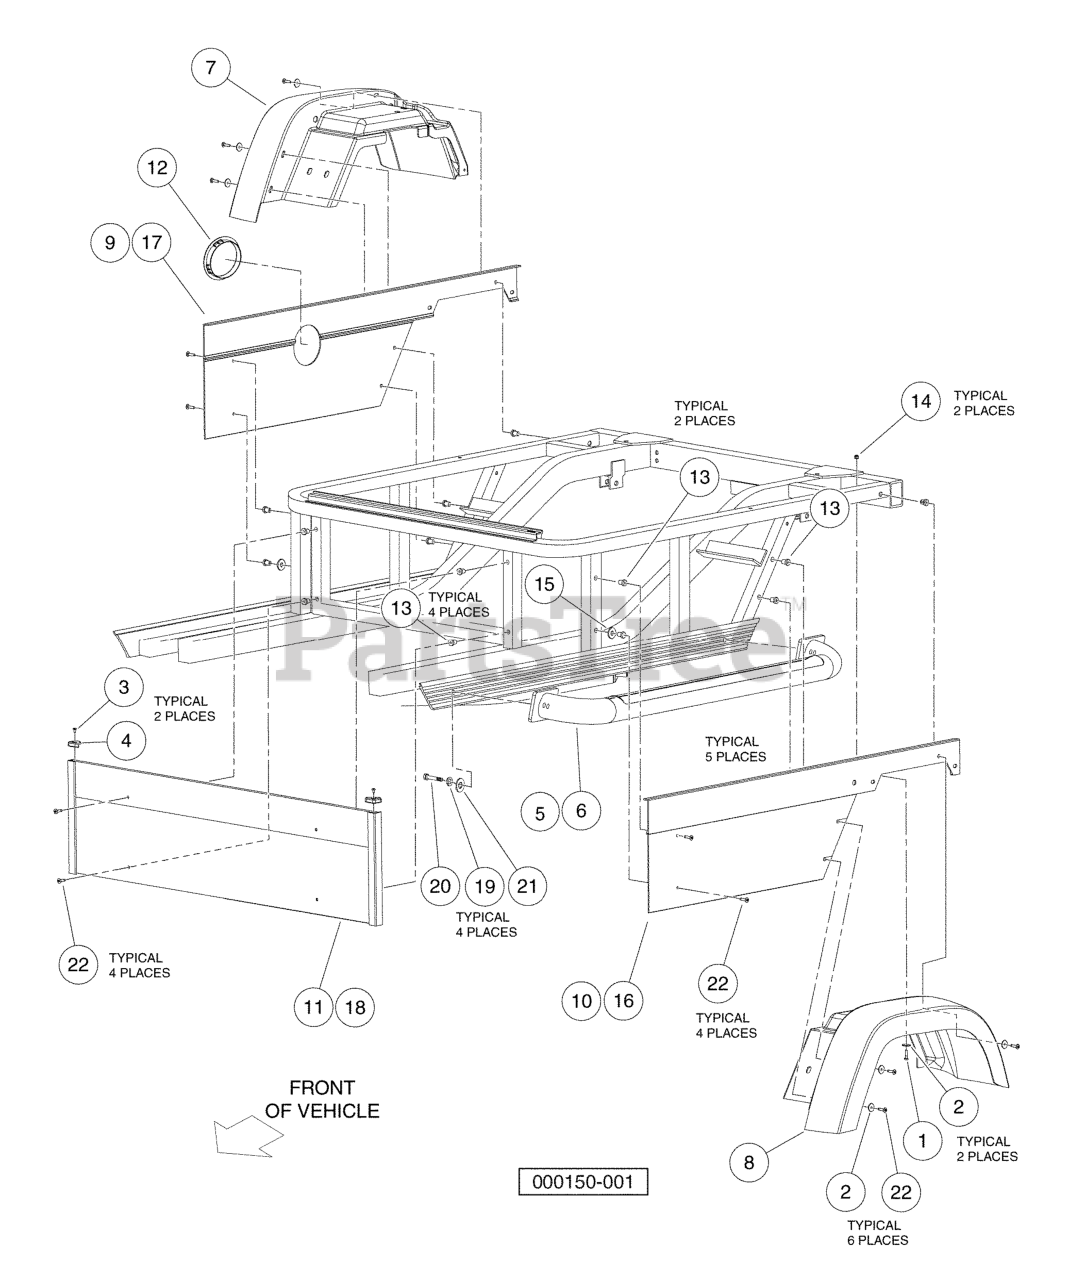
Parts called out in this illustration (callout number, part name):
4	CORNER CAP AWD
5	SIDE STEP BAR
6	SIDE STEP BAR
7	FENDER, RIGHT REAR
8	FENDER, LEFT REAR
9	PANEL, SIDE, WELDMENT, PASS
10	PANEL, SIDE, WELDMENT, DRV
11	PANEL, FRONT, WELDMENT
12	BEZEL, FUEL FILL
13	WELL NUT 1/4-20
14	NUT FLG, M6 X 1.0 NYLON
15	WASHER, M12 HARD REGULAR
16	SIDE PANEL, DRIVER, ORANGE
17	SIDE PANEL, PASS, ORANGE
18	FRONT PANEL ORANGE
19	WASHER,LOCK,HEL SP 3/8 REG
20	BOLT, 3/8-16 X 3.00 HEX HEAD
21	WASHER, 3/8 TYPE B FLAT
22	SCREW, 1/4-20 X 1.0 TRS HD MCH
